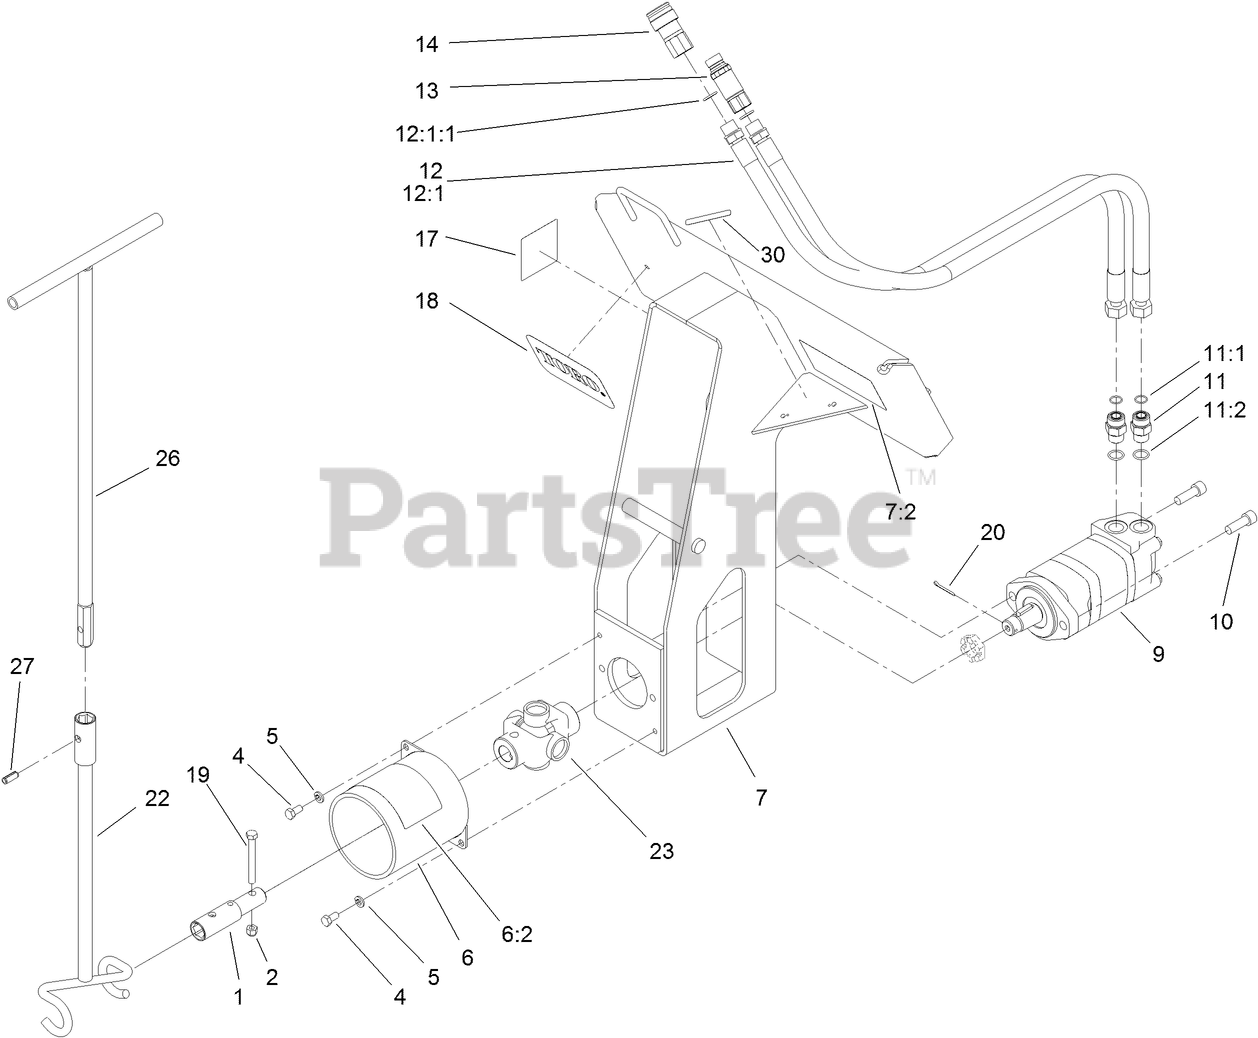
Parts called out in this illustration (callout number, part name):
1	COUPLER
2	NUT-LOCK, NI
4	SCREW-HH
5	WASHER-LOCK
6	SHIELD ASM
6:2	DECAL-WARNING
7	BORE FRAME ASM
7:2	DECAL-WARNING
9	MOTOR-HYDRAULIC
10	SCREW-HSH
11	FITTING-STRAIGHT
11:1	O-RING
11:2	O-RING
12	HOSE ASM
12:1	FITTING-STRAIGHT
12:1:1	O-RING
13	NIPPLE-CONNECT, PRESSURE
14	COUPLER-FACE, FLUSH
17	DECAL
18	DECAL
19	SCREW-HH
20	PIN-COTTER
22	TOOL-GUIDE, ROD
23	JOINT-UNIVERSAL
26	HANDLE-TOOL, GUIDE
27	PIN-ROLL
30	DECAL-WARNING
